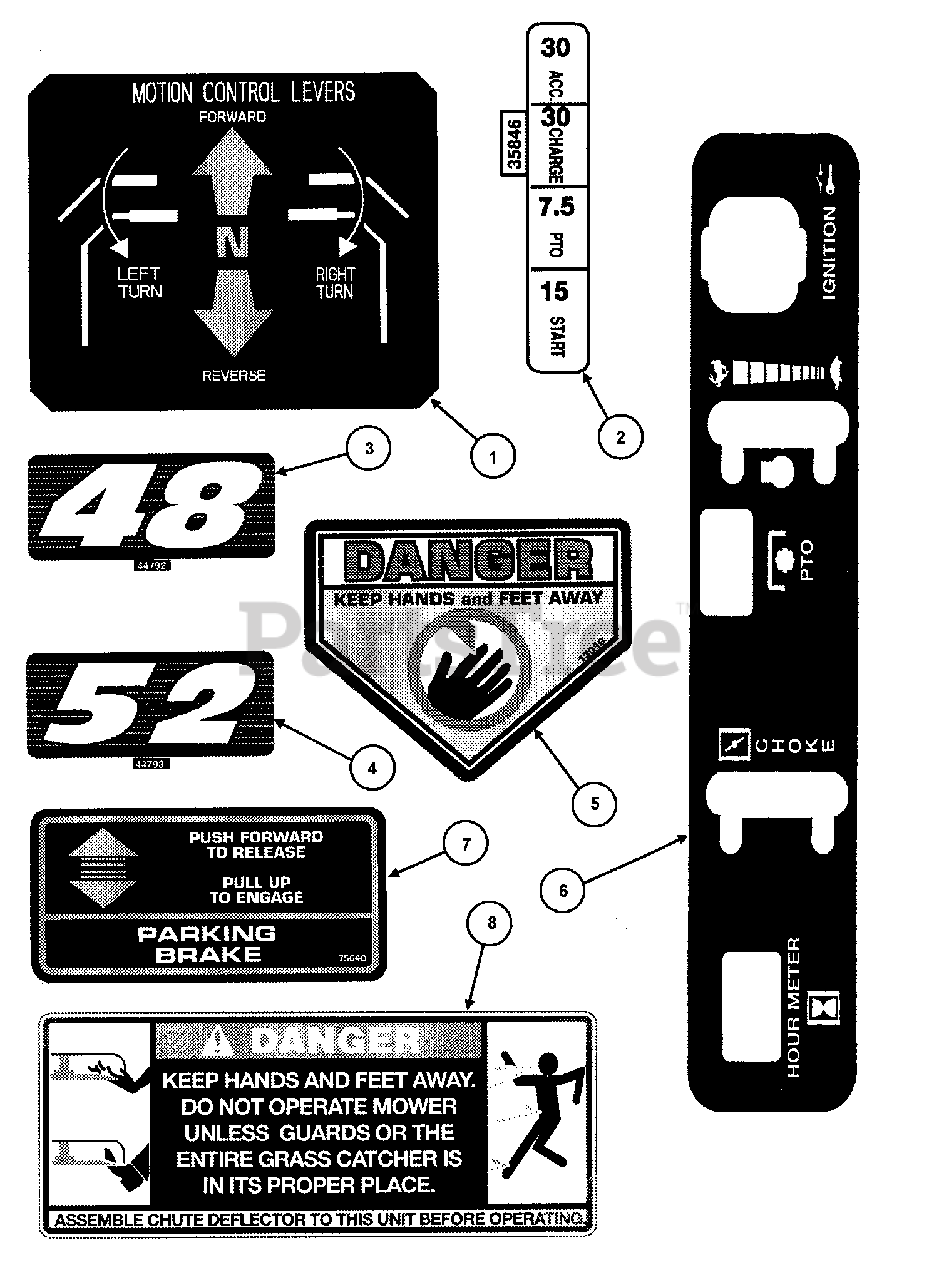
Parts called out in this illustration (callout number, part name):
1	DECAL, Motion Control Levers
2	DECAL, Fuse
3	DECAL, 48" Deck, Silver
4	DECAL, 52" Deck, Silver
5	DECAL, Danger, Cut Finger (CPSC)
6	DECAL, Control Panel, NZM
7	DECAL, Park Brake
8	DECAL, Danger- Guard Catcher
